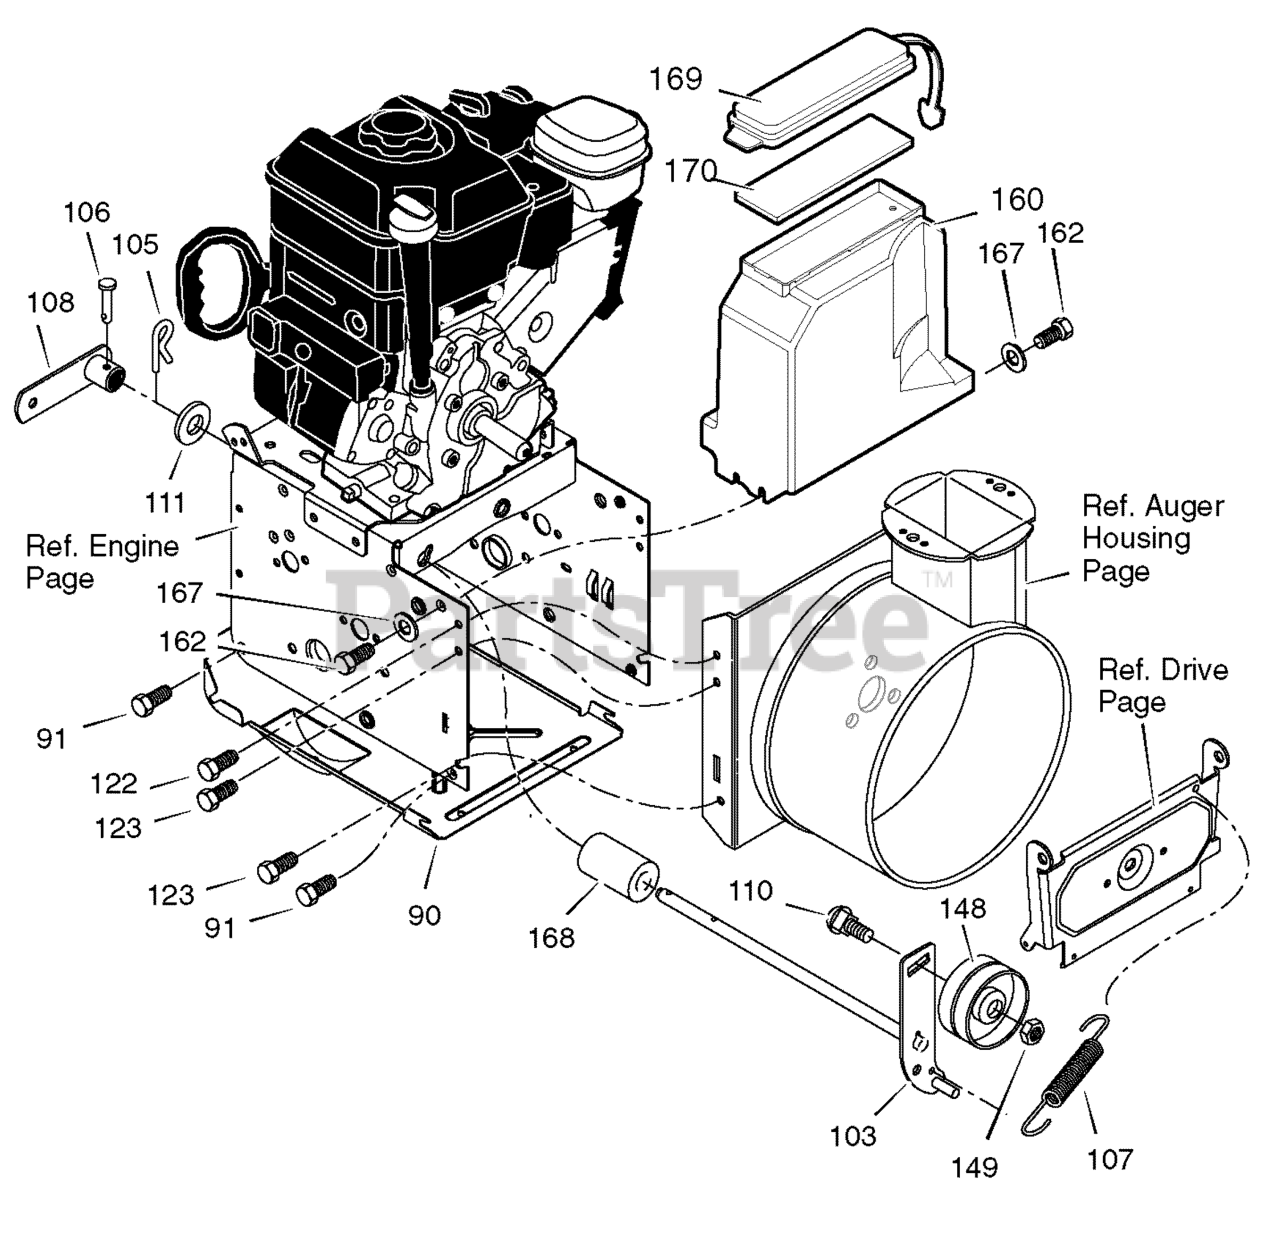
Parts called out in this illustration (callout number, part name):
90	COVER, BOTTOM
91	SCREW
103	IDLER, AUGER
105	PIN, HAIR
106	PIN, CLEVIS
107	SPRING, TENSION
108	SPRING ATTACH
110	BOLT, CARRIAGE
111	WASHER, FLAT
122	SCREW, TAP
123	SCREW, TAP
148	PULLEY, IDLER
149	NUT, JAM 3/8-16
160	COVER, BELT
162	SCREW, TAP
167	WASHER, FLAT
168	SPACER
169	LID, TOOL BOX
170	PAD, FOAM
